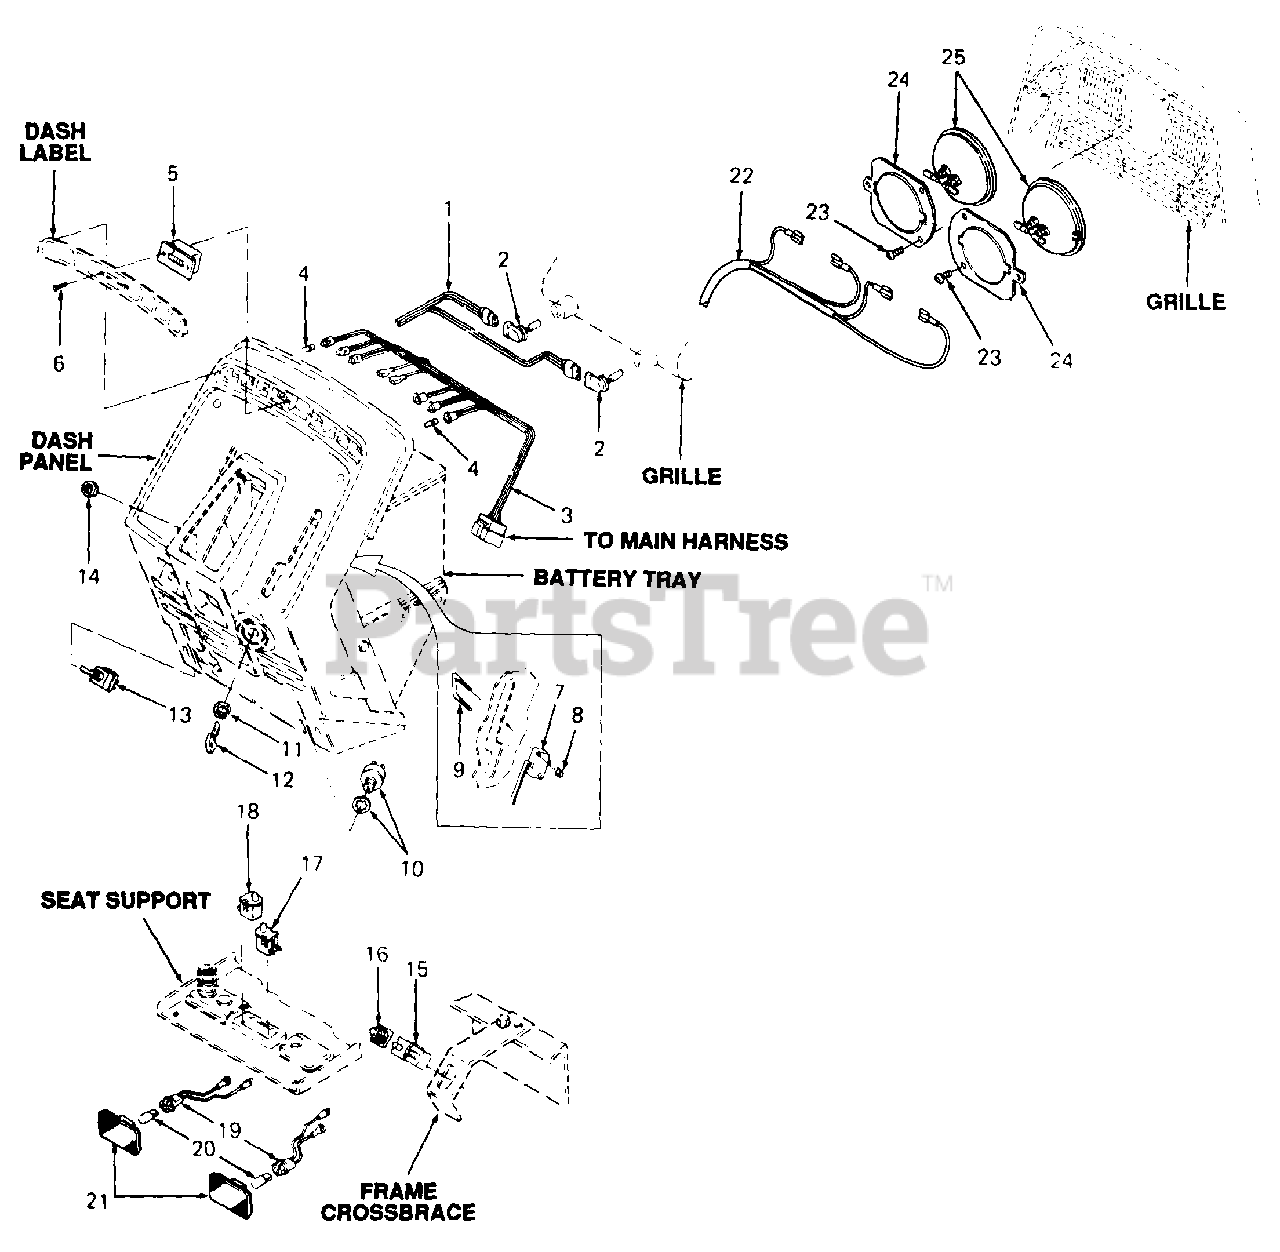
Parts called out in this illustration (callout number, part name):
1	Harness, Main Wire
2	Bulb, Head Lamp
3	Harness, Indicator Wire
4	Bulb, Indicator
5	Hour Meter
6	Screw, Truss Hd Tapp, #6 x .62 Lg
7	Switch, Reverse
8	Nut, Hex Insert Lock, #4-40
9	Screw, Switch
10	Switch, Ignition
11	Nut, Ignition Switch
12	Key, Ignition (Set of 2)
13	Switch, PTO
14	Nut, Hex, 1/2-27 x .100 Thk
15	Switch, Interlock
16	Boot, Switch
17	Switch, Snap Mount Normally Closed (Grey)
18	Switch, Snap Mount Normally Open (Black)
19	Cable Assy, Tail Light
20	Bulb, Tail Light
21	Lens Assy, Tail Light
22	Harness, Main Wire
23	Screw, Pan Hd Tapp, #12 x .50 Lg
25	Headlamp, Sealed Beam
